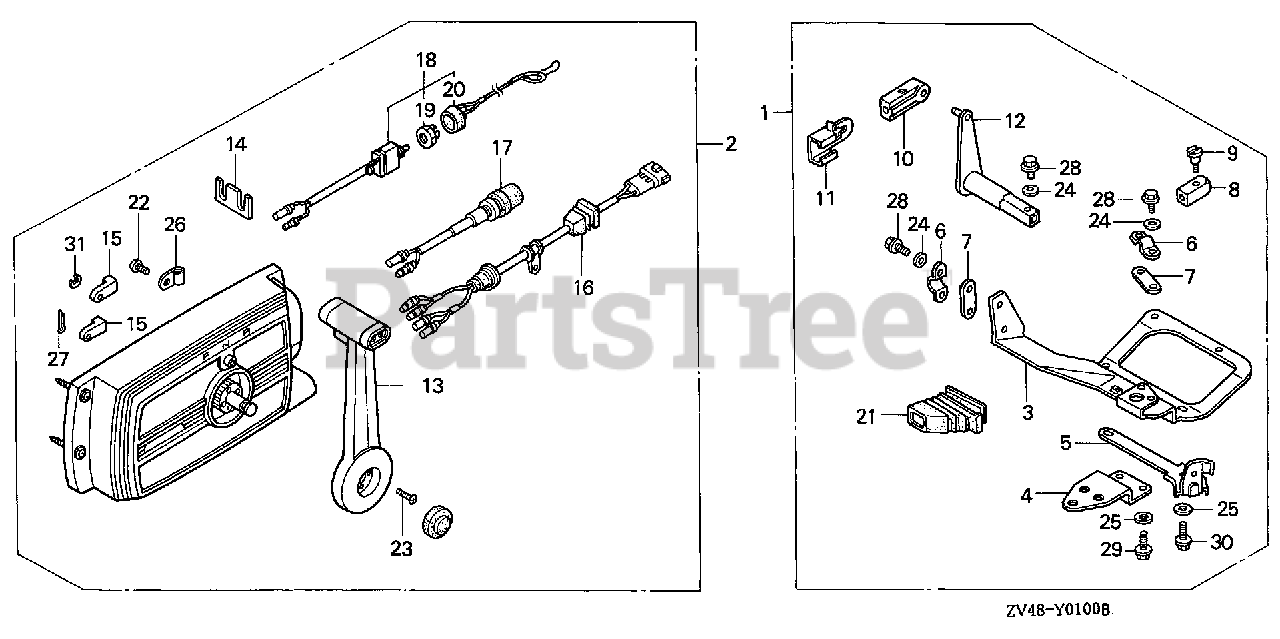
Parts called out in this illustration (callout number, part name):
1	CONTROL KIT, REMOTE
2	BOX KIT, OUTBOARD MOTOR CONTROL
3	BRACKET, STEERING
4	PLATE, STEERING
5	PLATE, STEERING STOPPER
6	CLAMP, CABLE
7	SHIM, CABLE CLAMP
8	NUT, CONTROL ADJUSTING
9	BOLT, CONTROL ADJUSTING
10	PIVOT, SHIFT
11	PLATE, LOCK
12	LEVER, GEARSHIFT
13	LEVER, CONTROL BOX
14	PLATE, CABLE CLAMP
15	PIVOT, SHIFT
16	CABLE ASSY., REMOTE CONTROL
17	SWITCH ASSY., ENGINE STOP
18	SWITCH ASSY., EMERGENCY STOP
19	NUT, CAP
20	CAP
21	RUBBER, SEALING
22	SCREW
23	SCREW
24	WASHER, PLAIN (5MM)
25	WASHER, PLAIN (6MM)
26	CLAMP, CORD
27	PIN, SPLIT (2.0)
28	BOLT, HEX. (5X12)
29	BOLT, HEX. (6X16)
30	BOLT, HEX. (6X18)
31	E-RING (5MM)
